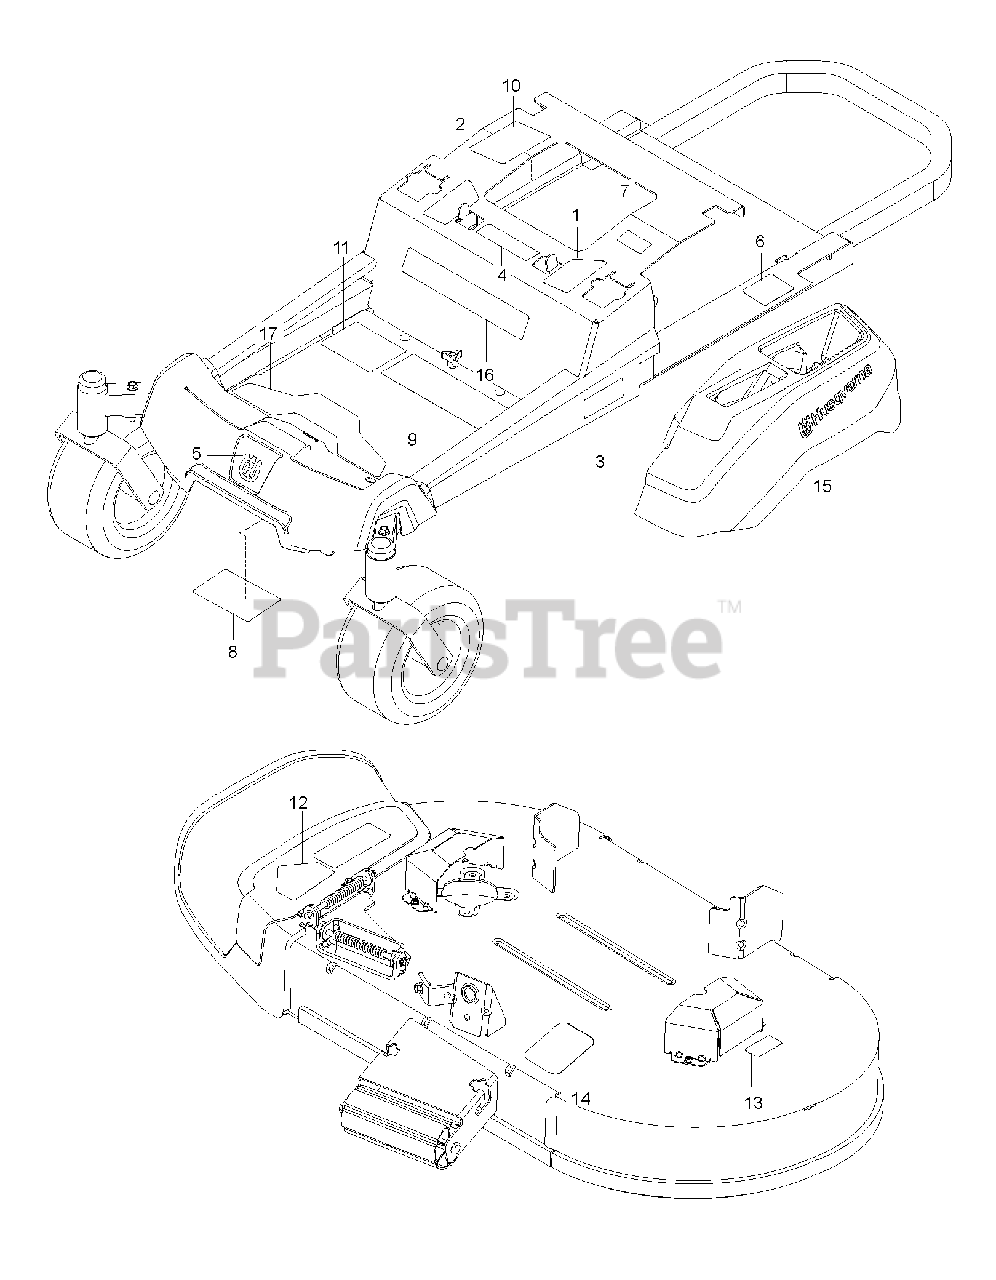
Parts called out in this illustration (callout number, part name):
1	DECAL.ZTR.RZ.THRTL/PRKBRK.V2.L
2	DECAL.ZTR.RZ.THRTL/PRKBRK.V2.R
3	DECAL.ZTR.SIDRAIL.Z242F.HUS
4	EURO DECAL-BATTERY WARNIN6
5	DECAL.BADGE.55MM.CROWNH.HUSQ
6	DECAL, DO NOT TOW
7	DECAL, EXITING MOWER
8	DECAL, SERVICE
9	DECAL ZTR WARNING DECAL DECAL.
10	DECAL.WARNING.CUST.RESP.E85.
11	DECAL.ZTR.STARTINS.READYSTART
12	DECAL.TRACT/ZTR.DECKWARN.HUSQ
13	DECAL.DECK.CLEARCUT.NOSTEP
14	DECAL, BELT ROUTING
15	DECAL.ZTR.SIDRAIL.Z242F.HUS
16	DECAL ZTR BRAND GRAPHIC DECAL.
17	PAD.RZ.FOOTREST.PLATE
